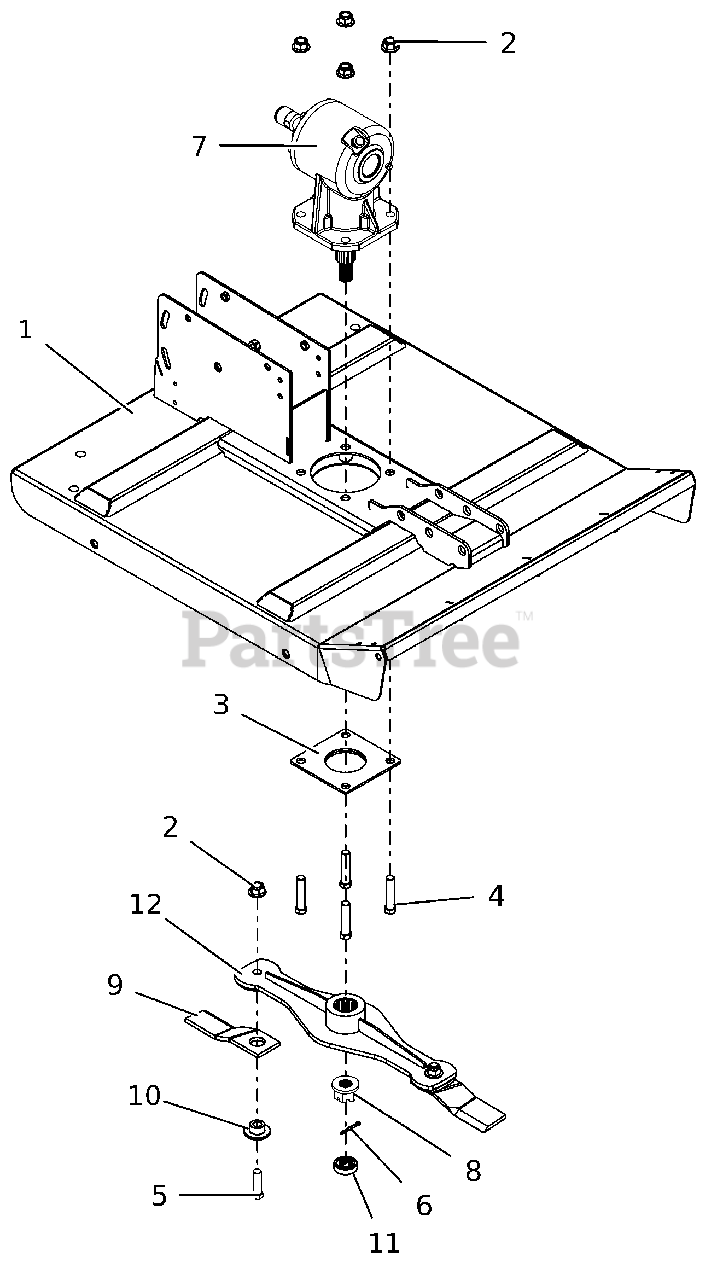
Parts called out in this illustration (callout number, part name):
1	WLDT, DECK 32 IN ROUGH CUT
2	NUT,NYL-FLG .63-11 GF ZCC
3	WLDMT, HUB SHIELD (RED)
4	BLT,HEX .63-11X2.75 G5 ZCC
5	BLT, HEX .62-11X2.00 G8 ZCC
6	PIN,CTR.18X1.50EXTPRSQCT ZC120
7	GEARBOX, 3034 BONDIOLI
8	NUT, FLANGE
9	KIT,RC MOWER REPLACEMENT BLADE
11	COLLAR, LOCKING 1.00-14
12	WLDMT, DISC RC
